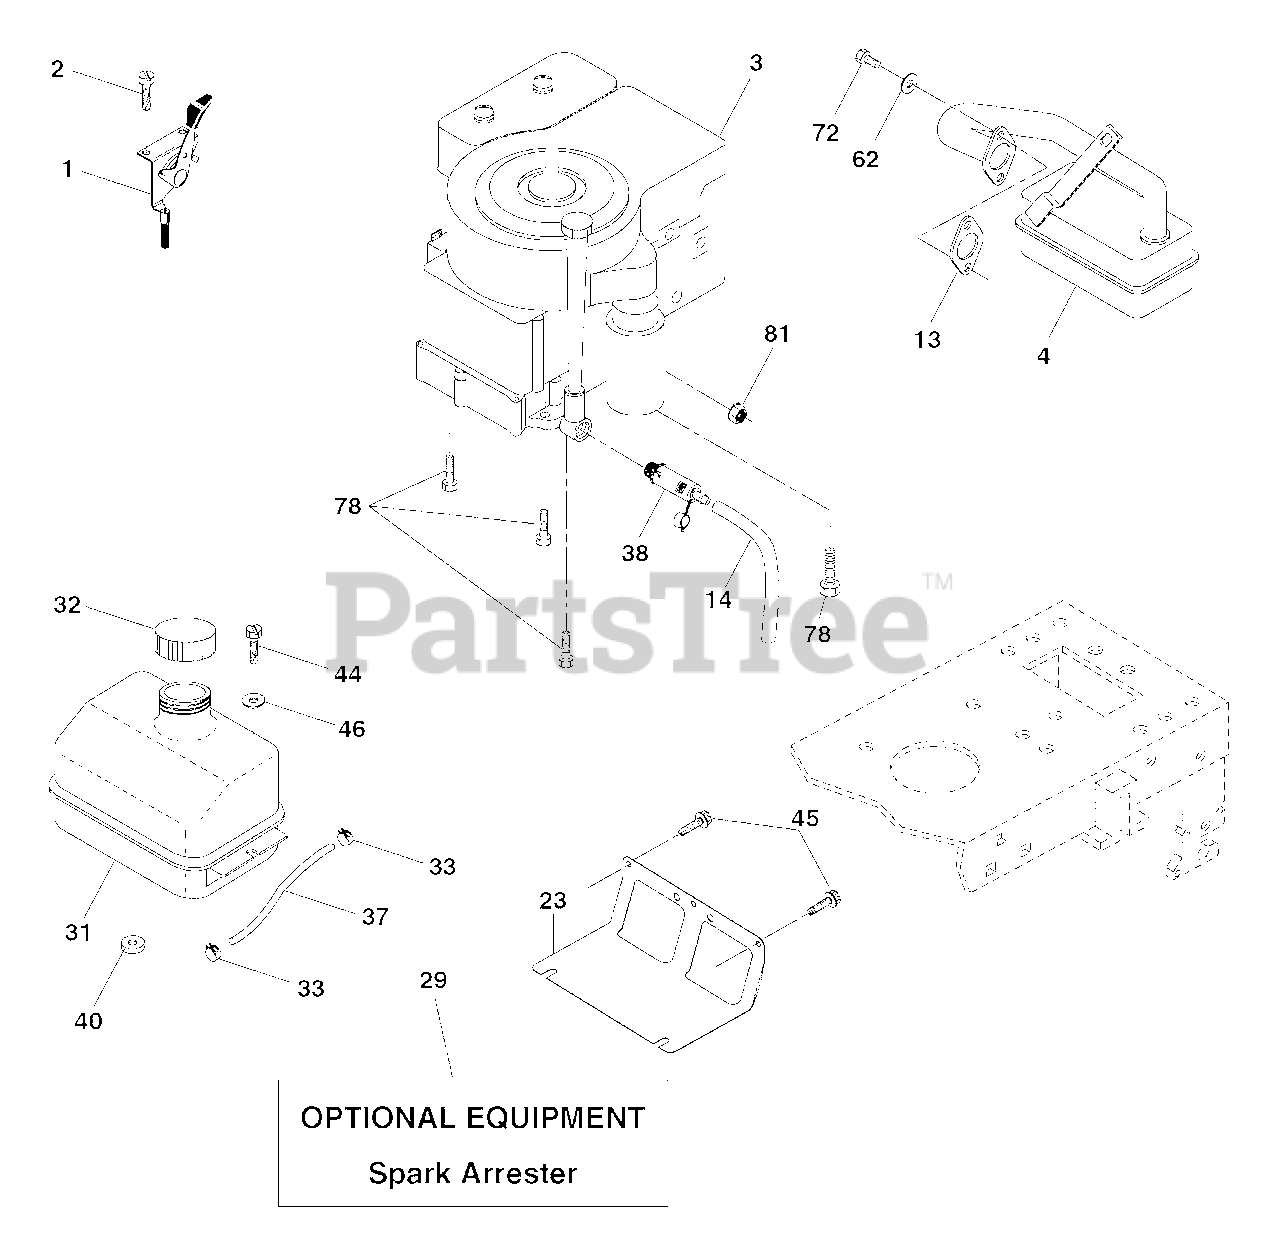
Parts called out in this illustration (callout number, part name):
1	Control Th/ch Flag
2	Screw Hex Thd Cut 1/4-20 x 1/2
4	Muffler Exhaust B&S
13	Gasket Eng 1 313 Id Tin Plated
14	Tube Drain Oil Easy
23	Shield BRN/DBR Guard
29	Kit Spark Arrestor (Flat Scrn)
31	Tank Fuel Front
32	Cap Asm Fuel
33	Clamp Hose
37	Line Fuel 20"
38	Plug Drain Oil
40	Bushing Snap Nyl Blk Fuel Line
44	Screw Thdrol 1/4-20 x 3/4
45	Screw Hex Wsh Thdrol 3/8-16
46	Washer 9/32 x 7/8 x 16 Ga.
62	Washer Lock 5/16
72	Screw Socket HD 5/16-18 x 3/4
78	Screw 3/8-16 x 1-1/4
81	Nut Keps Hex 1/4-20 unc
